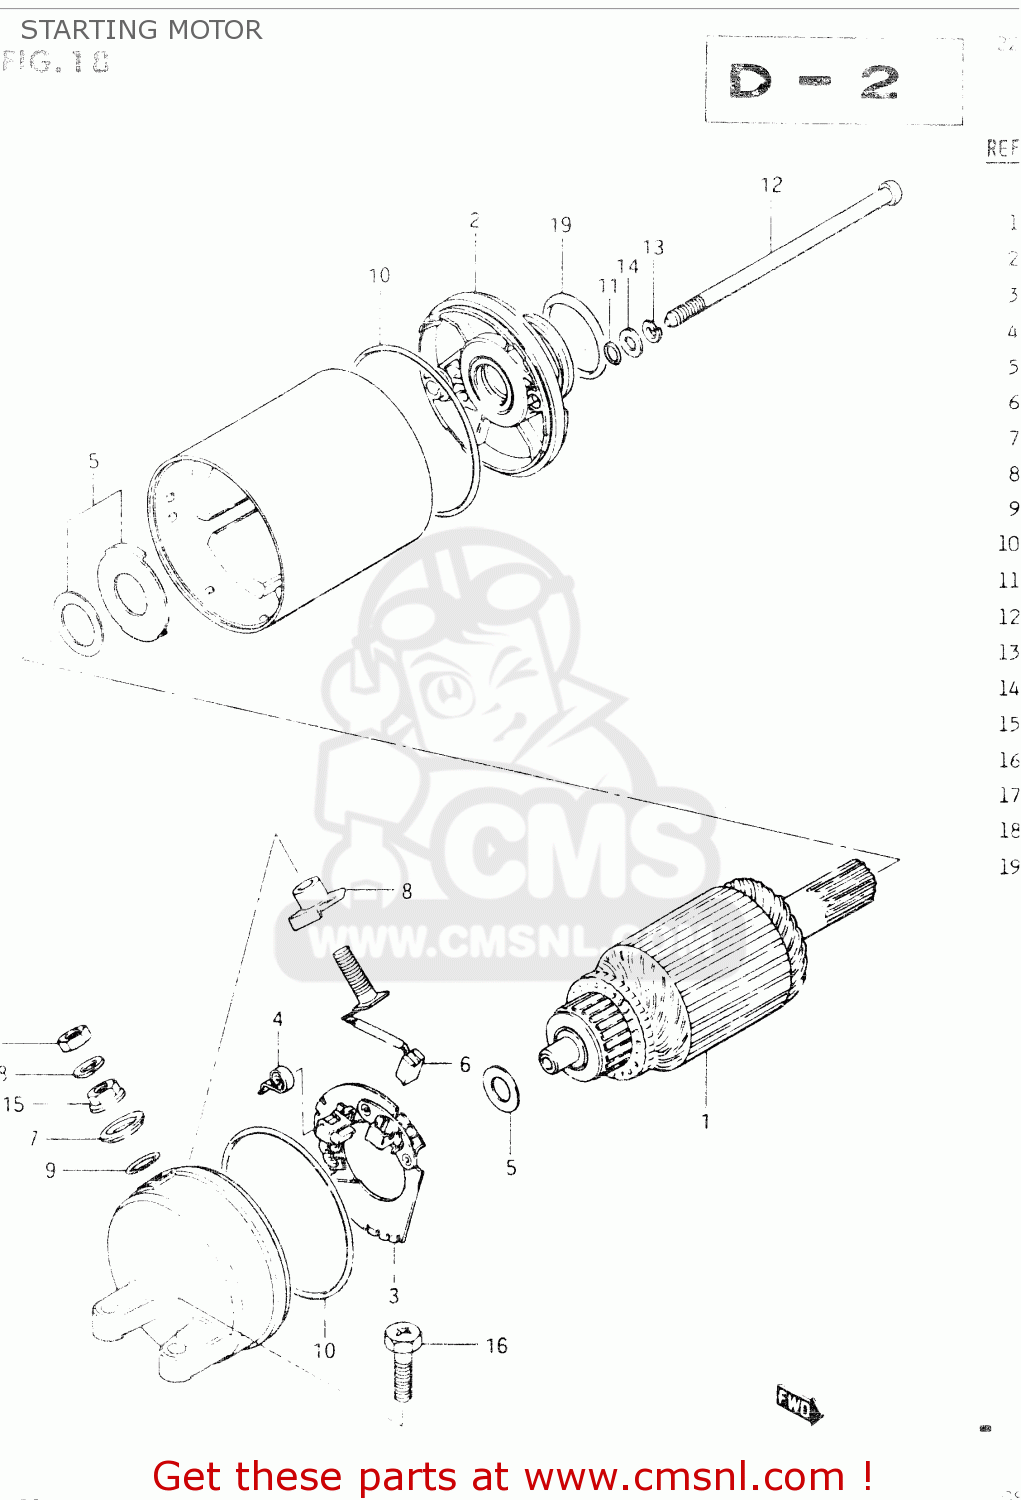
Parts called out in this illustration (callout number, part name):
1	ARMATURE
2	BRACKET SET,STARTING MOTOR
3	HOLDER,BRUSH
4	SPRING
5	SHIM SET,STARTING MOTOR
6	BRUSH SUB ASSY,STARTING MOTOR
7	BUSHING
8	BUSH,B
9	O RING
10	O RING
11	O RING
12	BOLT
13	LOCK WASHER
14	WASHER
15	NUT
16	SCREW (6X25)
17	NUT
18	WASHER,LOCK
19	O RING(D:3,ID:24.5)
